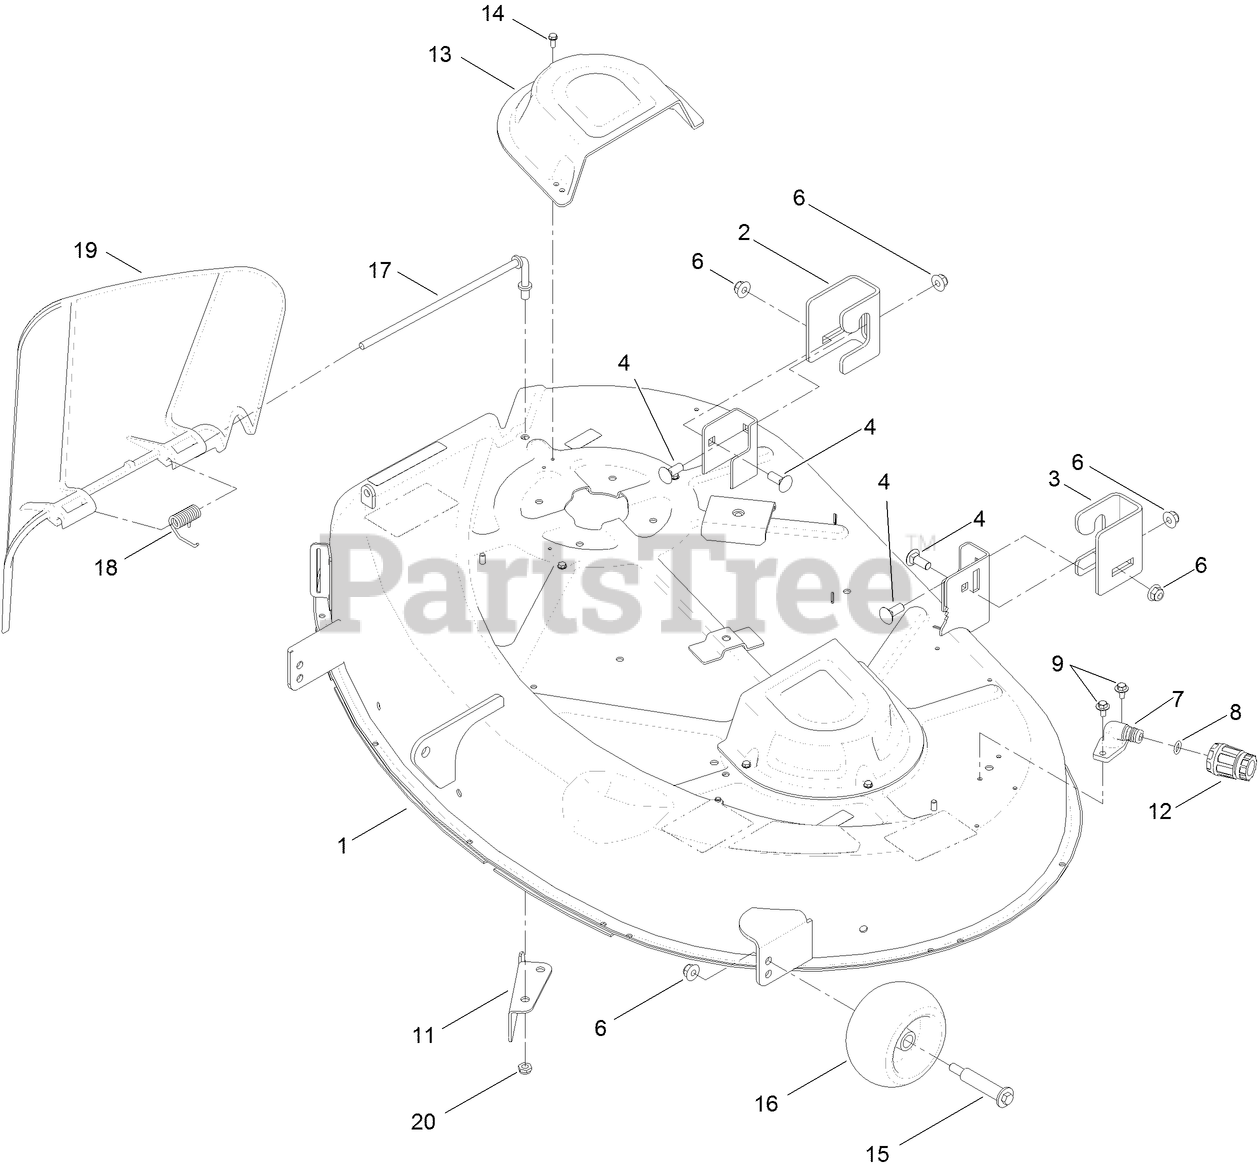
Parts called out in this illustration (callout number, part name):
1	42 INCH DECK AND DECAL ASM
3	BRACKET-HANGER, LH
4	BOLT-CARR
6	NUT-HF, NI
8	O-RING
9	SCREW-HHFTF
11	BAFFLE-CUTOFF
12	CONNECTOR-HOSE
13	COVER-BELT
14	SCREW-TAPTITE
15	BOLT-SHOULDER
16	ROLLER-SCALP, ANTI
17	ROD-PIVOT
18	SPRING-TORSION
19	DEFLECTOR
